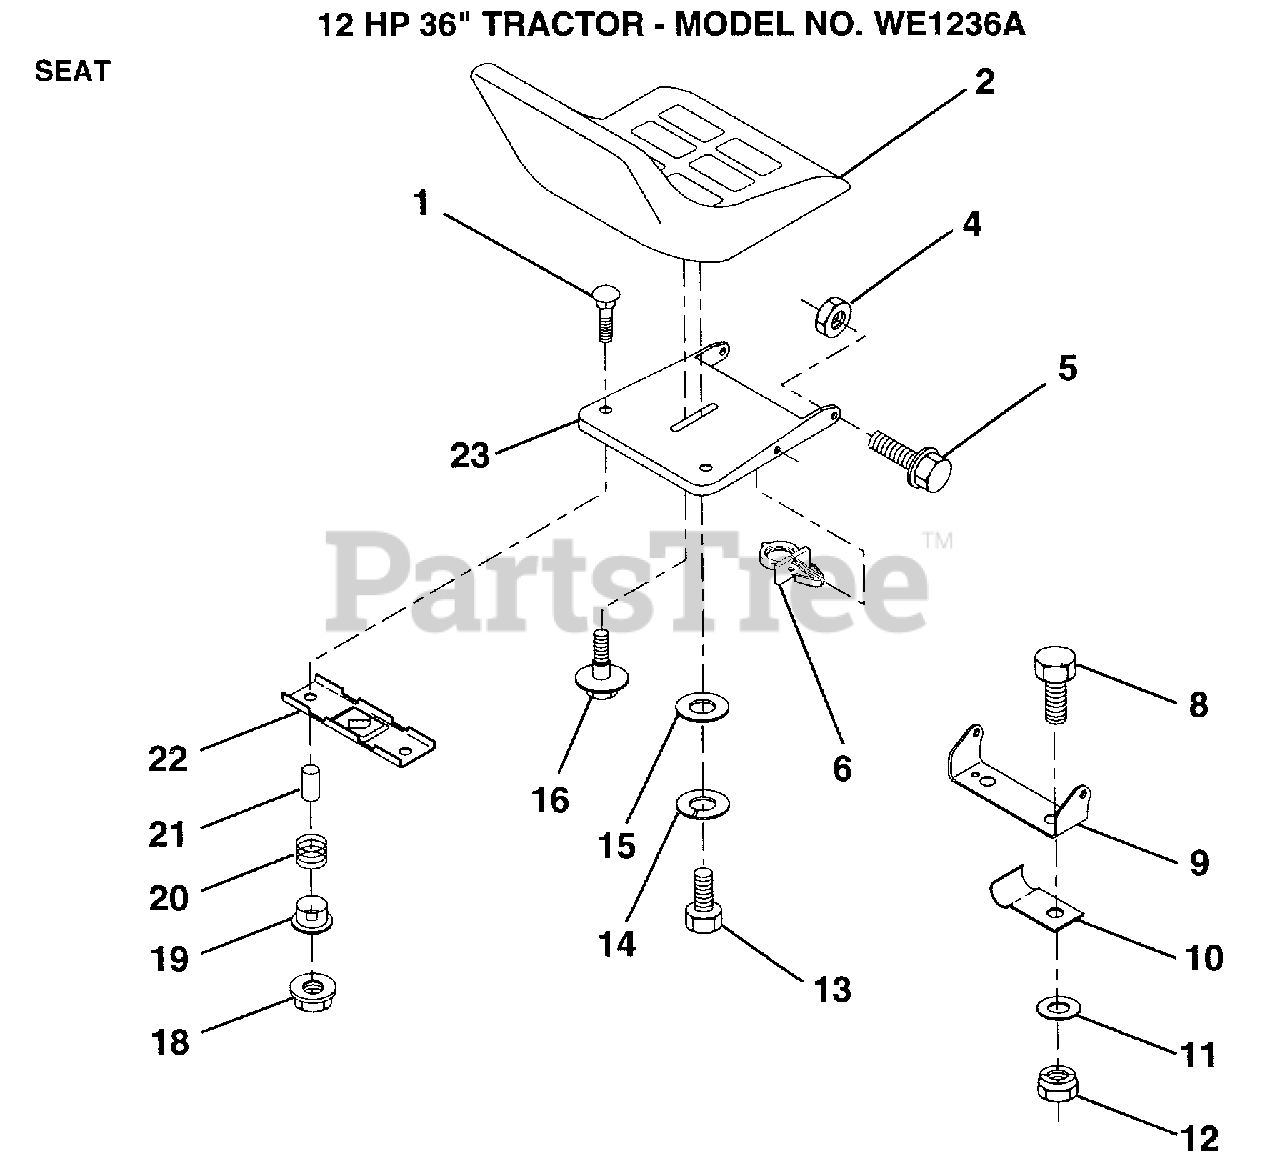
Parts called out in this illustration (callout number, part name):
4	NUT
5	BOLT.SHLD.5/16-18
6	CLIP PUSH - IN
8	BOLT
9	BRACKET PVT SEAT
10	"CLIP,INSULATOR"
11	WASHER
12	NUT
13	BOLT
14	LOCKWASHER
15	WASHER
16	"BOLT,SHOULDER"
19	BUSHING
20	SPRING
21	SPLIT SPACER
22	BRKT SWITCH
